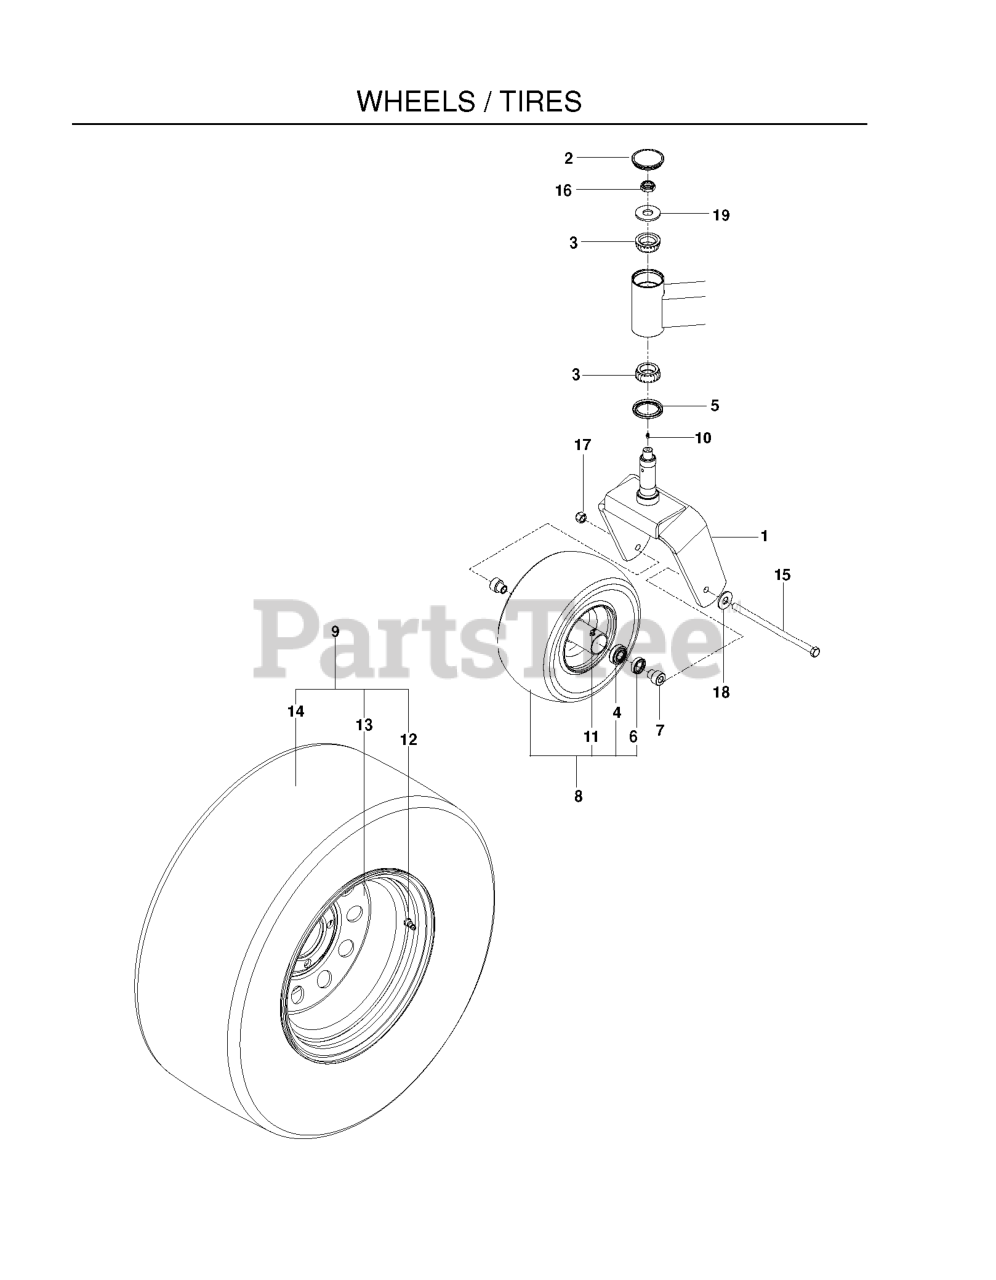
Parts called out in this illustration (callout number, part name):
1	FORK.CASTER.ORANGE
3	BEARING W/CUP TAPPER ROLLER
4	TAPERED BEARING W/RACE
5	SEAL, BEARING
7	AXLE SPACER
8	TIRE, 13 X 6.5-6 NO FLAT
9	WHEEL/TIRE.ASM.24X12-12.SILVER
11	ZERK
12	VALVE STEM TR-412
13	RIM, 12 X 8.5 W/1.75 NEG OS
14	TIRE.24X12-12.TURF.MASTER
15	HEX SCREW 1/2-13 X 9.5 GR5
16	NUT, 3/4-16 HEX THIN NYLOC ZD
17	NUT, 1/2-13 HEX FLG NYLOC ZD
18	WASHER 1/2" FLAT
19	WASHER, 3/4 HARDENED
